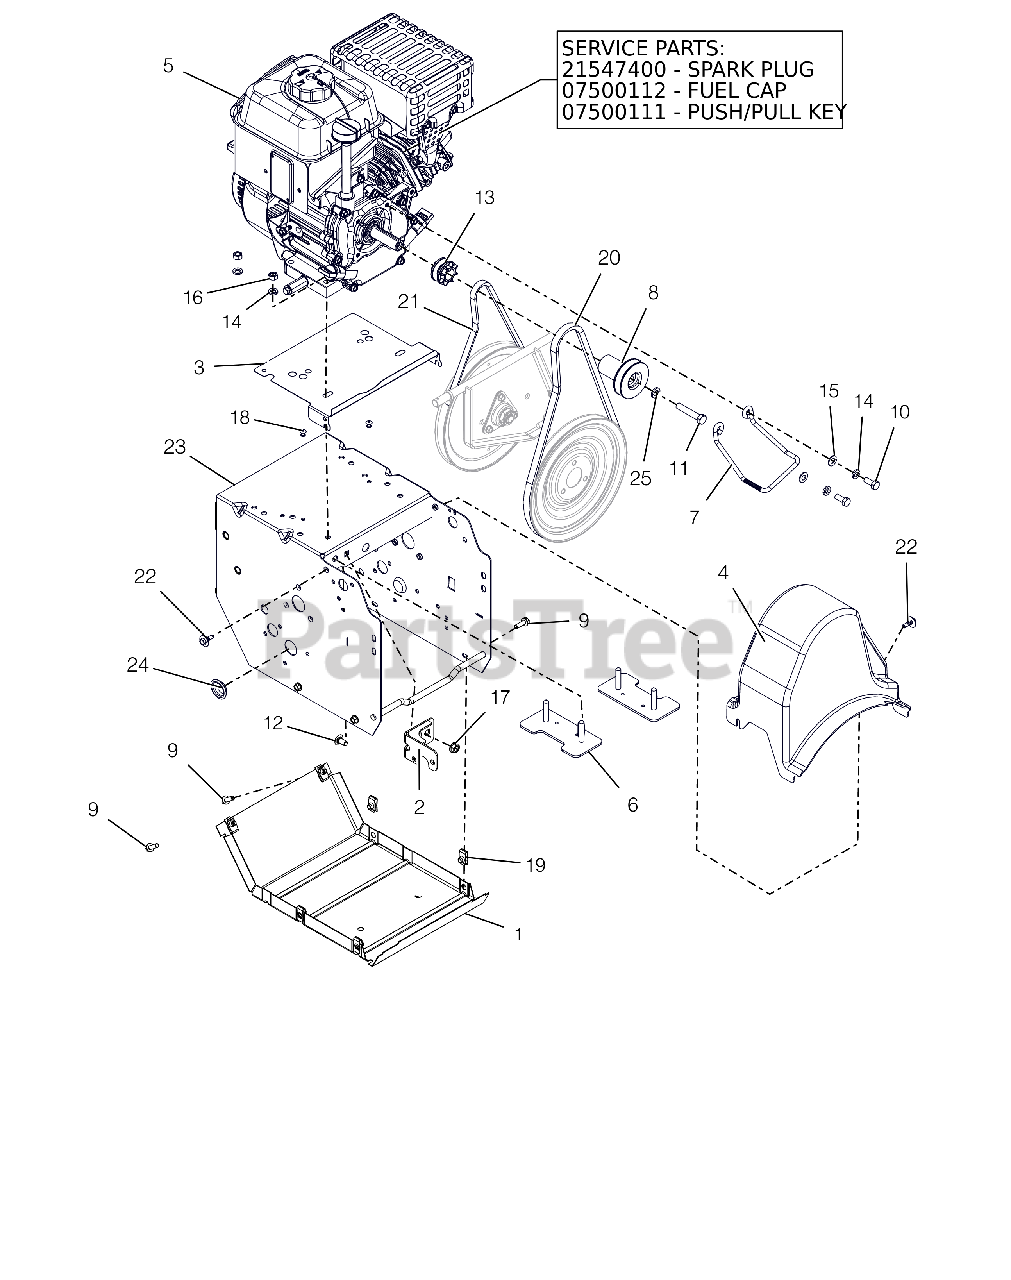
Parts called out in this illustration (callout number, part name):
1	COVER, BOTTOM
2	WELDMENT, FRAME BRACKET
3	BAFFLE, COMPACT
4	COVER, COMPACT BELT
5	ENGINE, SNO-TEK 136 RECL
5	PLUG, SPARK
5	CAP, FUEL TANK BLACK
5	KEY, PUSH/PULL LCT (2/PACKAGE)
6	STRAP, ENGINE BOLT-WELDMENT
7	BELT FINGER
8	SHEAVE, AUGER DRIVE
9	BLT-HEX .25-20X.75 HWH YZ GR5
10	BLT-HEX .31-24X.75 YWZC GR5
11	BLT-HEX .38-24X2.0 YWZC
12	@BLT-RHDSSQNK .31-18X.62 G5YZ
13	SHEAVE, TRACTION
14	WSHR-LK .312X.097 HVY YWZC
15	@WSHR-FL-STL.344X.688X.065YWZC
16	@NUT-HEX .31-18 YWZC
17	@NUT-LK-TOP-FLG .31-18 YWZC
18	RVT-POP .187 YZ
19	NUT-RTNR .25-20X.56
20	V-BELT, HA-RAW EDGE
21	V-BELT, 3L-WRAPPED
22	SCR-TAP .25-20X.5 CAPTIVE
23	FRAME, MAIN
24	PLUG, HOLE - 1.00" FLEXTEMP
25	@WSHR-LK .38X.094 REG YWZC
